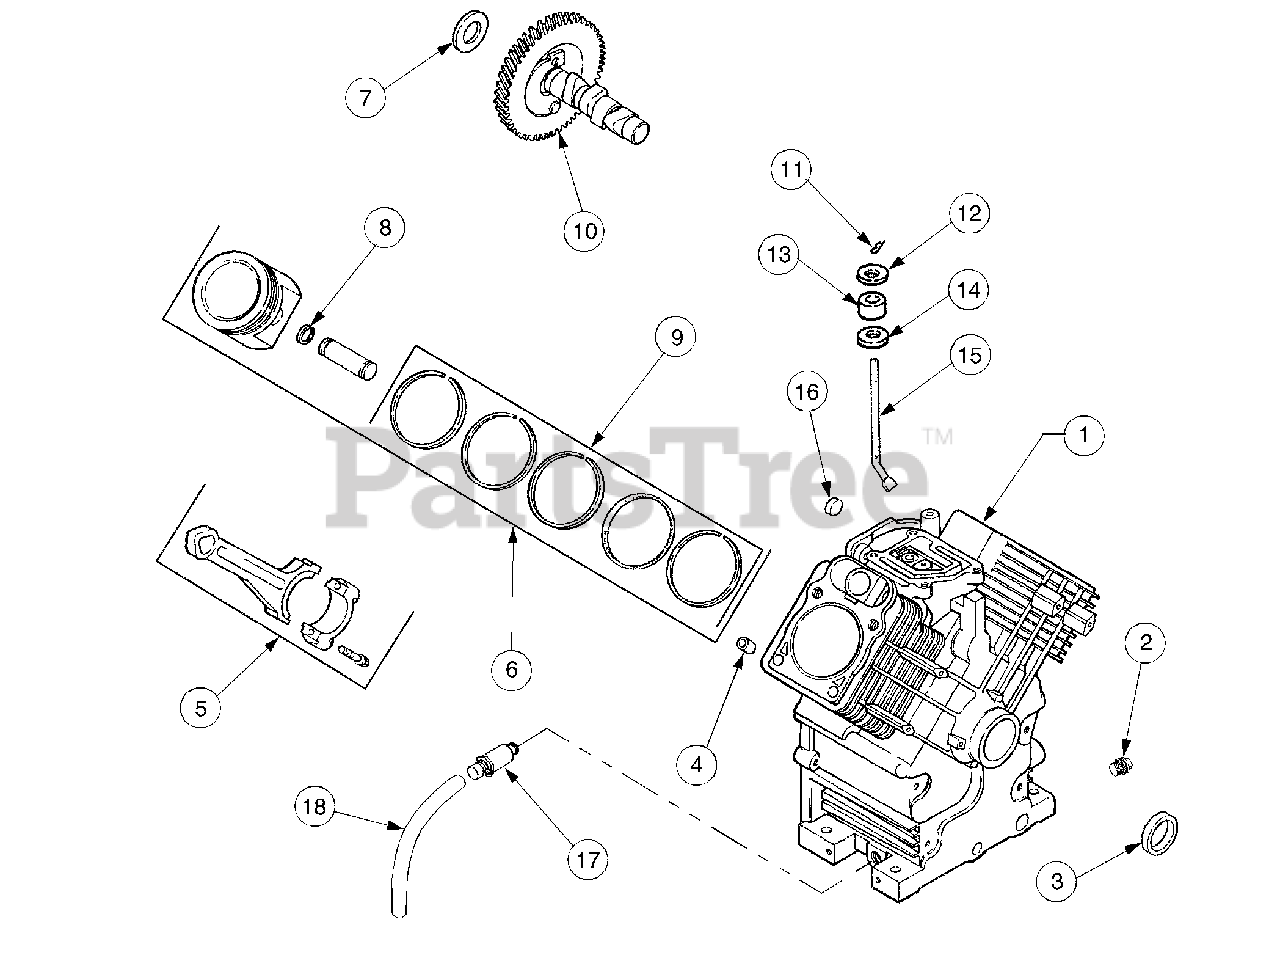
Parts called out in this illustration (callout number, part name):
1	Cylinder Block, (Miniblock) (6mm)
2	Plug, Hex Hd, 3/8
3	Seal, Front Oil
4	Pin, Locating Dowel
5	Rod, Connecting, Std
6	Piston w/Ring Set, Std
7	Shim, Camshaft, .0320 (Red)
8	Retainer, Piston Pin
9	Ring Set, Std
10	Camshaft Assembly
11	Pin, Hitch (6mm)
12	Washer, Plain (6mm)
13	Seal, Gov. Cross Shaft (6mm)
14	Washer (Bottom) (6mm)
15	Shaft, Gov. Cross (6mm)
16	Plug, Cup
17	Drain, Oil
18	Hose, Oil Drain
